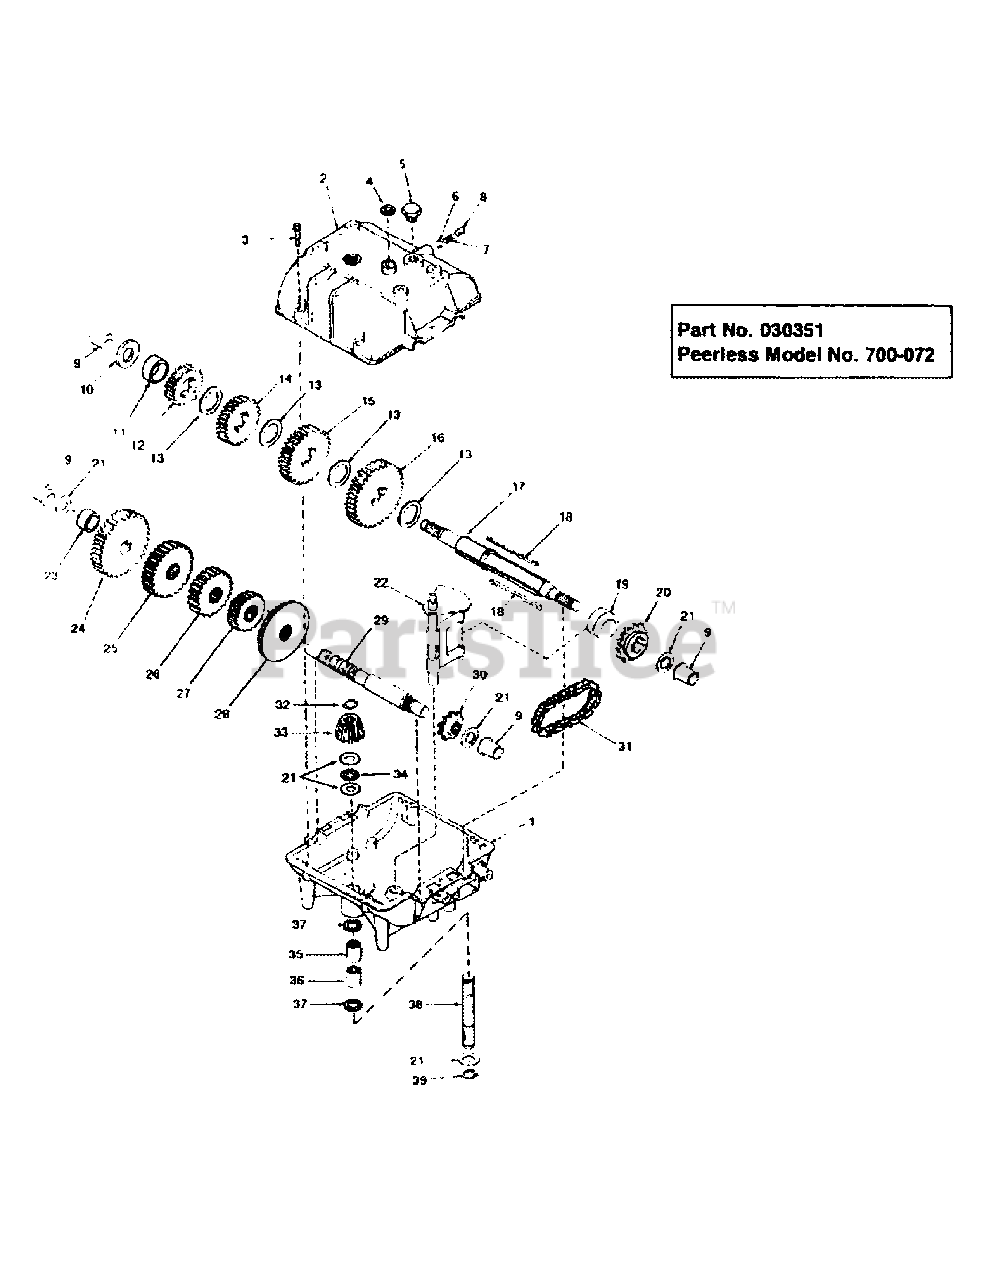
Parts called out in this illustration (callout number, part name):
1	transmission case
2	transmission cover
3	cap screw
4	seal, square cut
5	threaded plug
6	steel ball, 5/16" dia
7	spring
8	set screw
9	flange bushing
10	thrust washer
11	spacer
12	spur gear (30 teeth)
13	thrust washer
14	spur gear (32 teeth)
15	spur gear (35 teeth)
16	spur gear (37 teeth)
17	shaft-output/brake
18	key, shift
19	shift collar
20	sprocket (18 teeth)
21	thrust washer
22	rod & fork, shift
23	spacer
24	spur gear (20 teeth)
25	spur gear (18 teeth)
26	spur gear (15 teeth)
27	spur gear (12 teeth)
28	spur gear (42 teeth)
29	counter shaft
30	sprocket (9 teeth)
31	roller chain (#41, 24 links)
32	retaining ring
33	bevel pinion, input
34	thrust bearing
35	needle bearing
36	needle bearing
37	o-ring
38	input shaft
39	retaining ring
